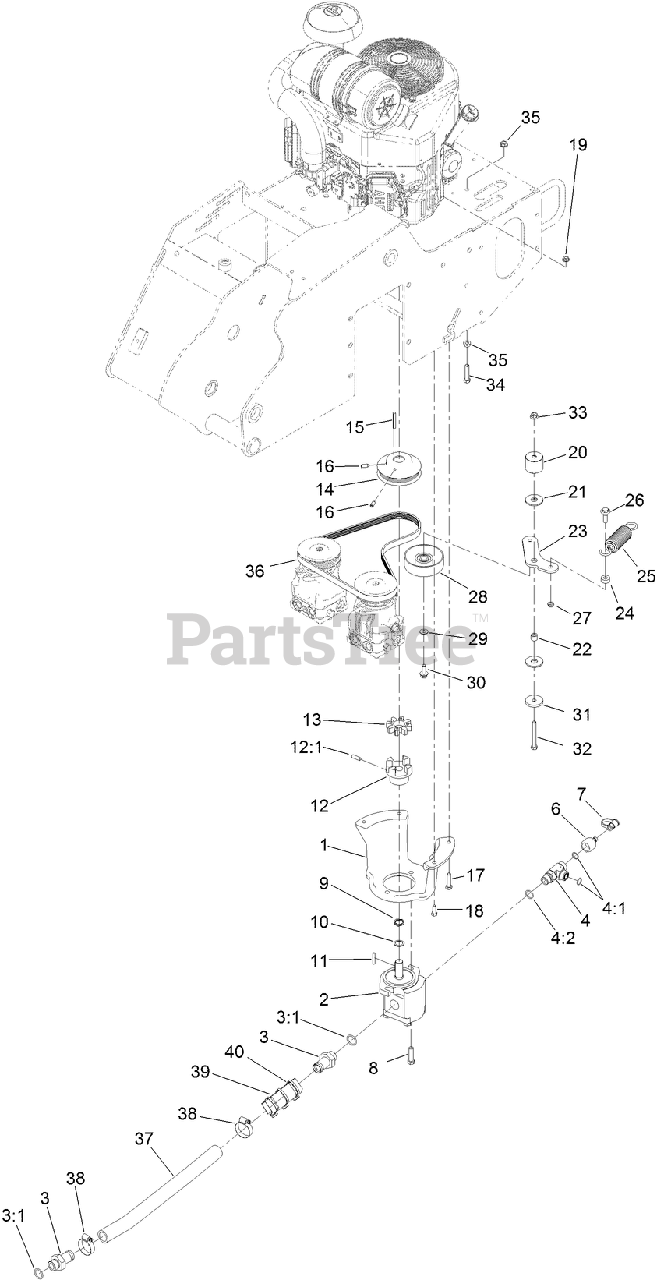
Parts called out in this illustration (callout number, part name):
1	MOUNT-PUMP
2	GEAR PUMP ASM
3	FITTING
3:1	O-RING
4	FITTING-TEE
4:1	O-RING
4:2	O-RING
6	NIPPLE
7	CAP-DUST
8	SCREW-HH
9	WASHER-WAVE
10	WASHER-THRUST
11	KEY-SQUARE
12	COUPLER-FLEX
12:1	SCREW-SET
13	COUPLER-SPIDER
14	PULLEY-ENGINE
15	KEY-SQUARE
16	SCREW-SET, HSH
17	SCREW-HH
18	SCREW-HH
19	NUT-HF
20	SPACER-IDLER
21	WASHER-FRICTION, COMPOSITE
22	BUSHING-LEVER, LIFT
23	ARM-IDLER
24	SPACER
25	SPRING-EXTENSION
26	SCREW-SHOULDER, HWH
27	NUT-LOCK, NI
28	PULLEY-IDLER
29	WASHER-FLAT
30	SCREW-HHF
31	WASHER-PLAIN
32	SCREW-HH
33	NUT-HF, NI
34	SCREW-HH
35	NUT-HHF, WHIZ
36	BELT-V
37	HOSE-SUCTION
39	PROTECTOR-HOSE
40	TIE-CABLE
